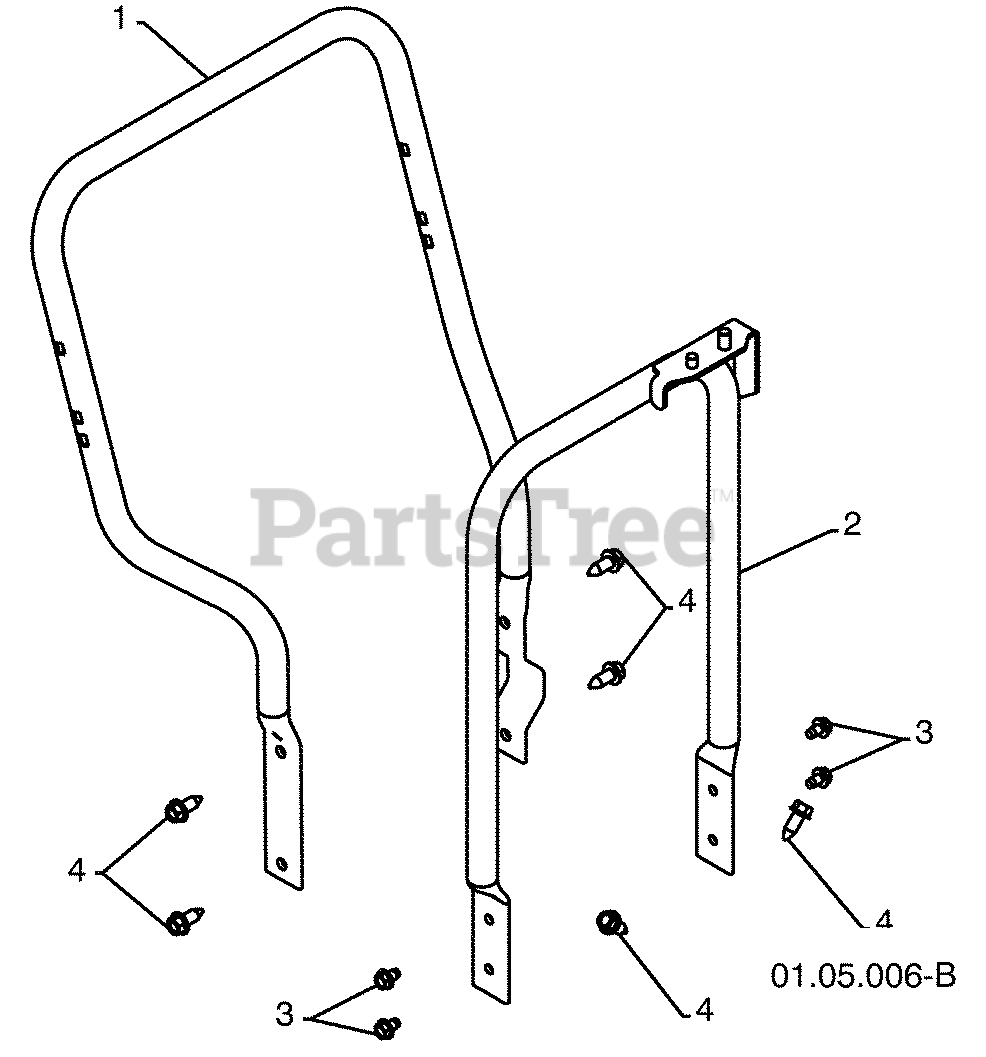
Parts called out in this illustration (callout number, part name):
1	LOWER TUBE GRAY
2	PIVOT SUPPORT
3	BOLT 5/16-18 X .75
4	SCREW 3/8-16 X 1.00
